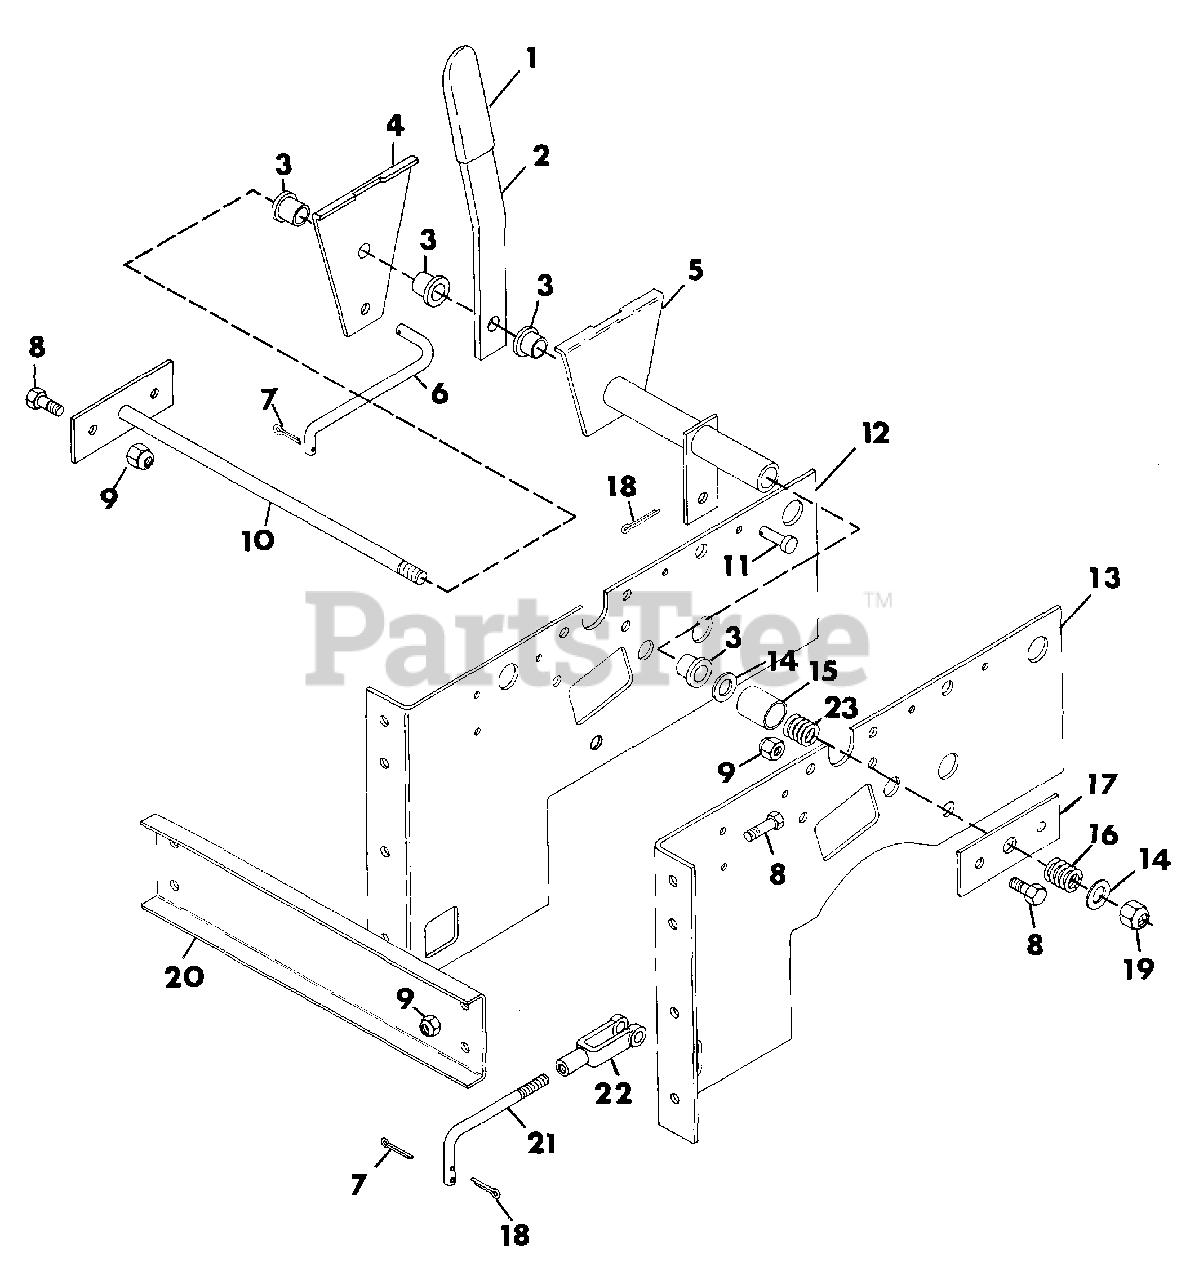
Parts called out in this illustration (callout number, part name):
1	GRIP, HANDLE
2	LEVER, SHIFTER
3	BUSHING, CABLE GUIDE PULLEY
4	WELDMENT, SHIFT LEVER R.H.
5	WELDMENT, SHIFT LEVER L.H.
6	ROD, GEAR SHIFT
7	PIN, COTTER HAIR
8	BOLT, HEX 3/8-16X.875
9	NUT, LOCK 3/8-16
10	WELDMENT, CROSS SHAFT
11	PIN, CLEVIS .375X.948
12	BRACKET, CONTROL MOUNT R.H.
13	BRACKET, CONTROL MOUNT L.H.
14	WASHER, FLAT .531X1.062X.095
15	SPACER, #2 SHAFT
16	SPRING, COMPRESSION 1.00X.78X338 LB/IN
17	PLATE, CROSS SHAFT
18	PIN, COTTER .09X.75
19	NUT, LOCK 1/2-13
20	BRACKET, HYDRAULIC TANK
21	ROD, GEAR SHIFT
22	CLEVIS, 3/8-24 ADJUSTABLE
23	SPRING, COMPRESSION 2.75X.625X34 RATE
